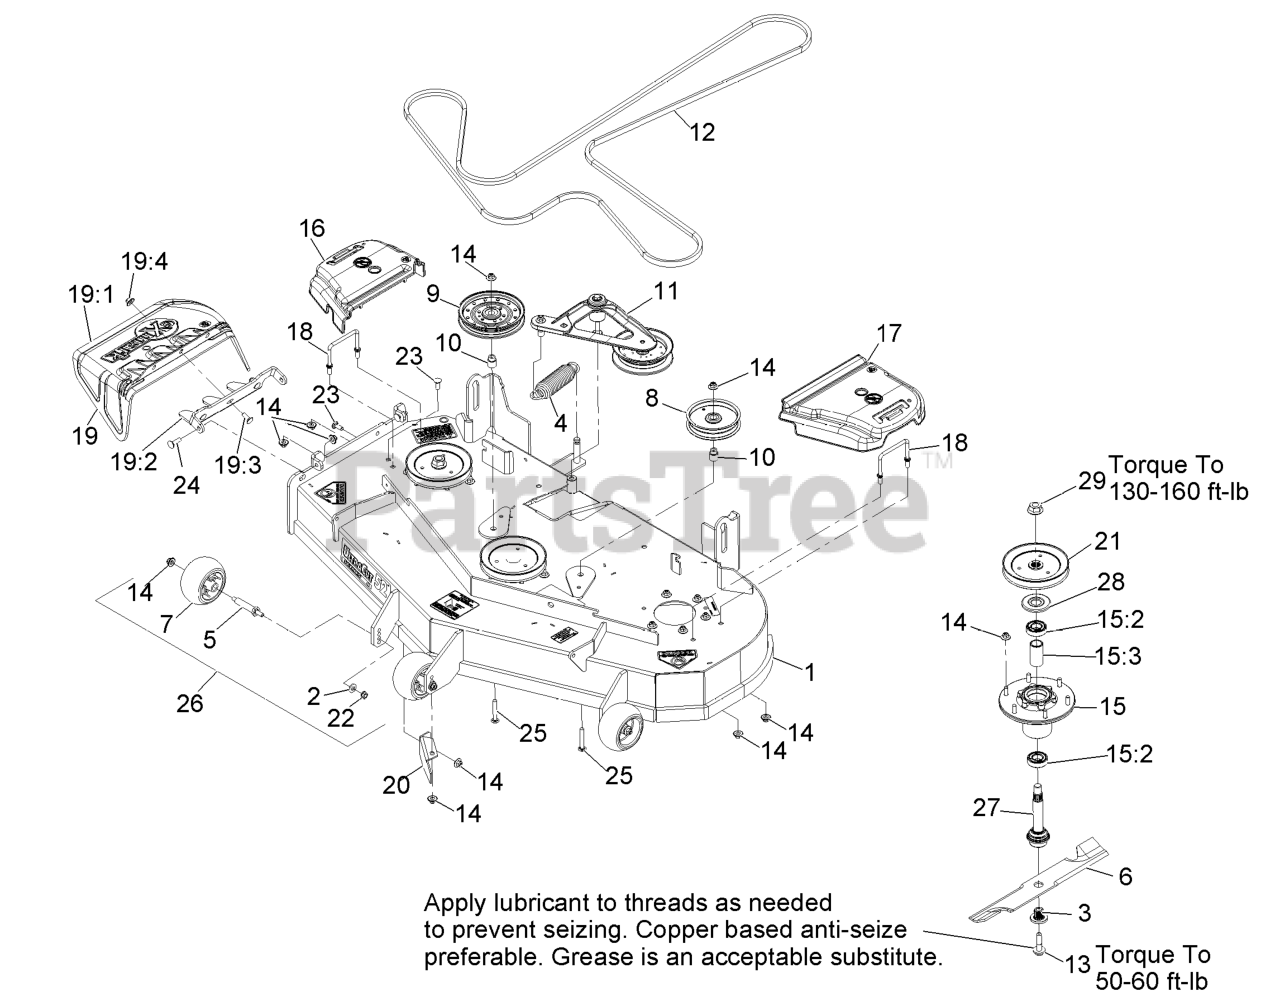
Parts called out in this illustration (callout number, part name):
1	ASM,524 DECK WITH DECALS
2	WASHER-BELLEVILLE
3	BUSHING,SPLINED
7	ROLLER-SCALP, ANTI
8	PULLEY-IDLER
10	BUSHING-IDLER
11	DECK IDLER ASM
13	SCREW,SEMS 1/2-20 X 2.19
14	Nut-Nyloc 3/8-16 Flg
15	ASM-CUTTER HSG WITH BEARINGS
15:2	BEARING-BALL
15:3	SPACER-BEARING
16	COVER-BELT, RH
17	COVER-BELT, LH
18	WIREFORM-COVER
19	ASM,DISCHARGE CHUTE
19:1	CHUTE,DISCHARGE
19:2	BRACKET,DISCHARGE CHUTE
19:3	SCREW-CARR
19:4	Nut-Nyloc 3/8-16 Flg
20	BAFFLE,DISCHARGE 52/60
21	SHEAVE,BLADE DRIVE 6.50
22	NUT-HHF, WHIZ
23	SCREW-CARR
24	Bolt-Carriage 3/8-16 X 1 1/4
25	SCREW-CARR
27	ASM-SPINDLE AND SEAL
28	GUARD,BEARING TOP .989
29	NUT-FLANGE
